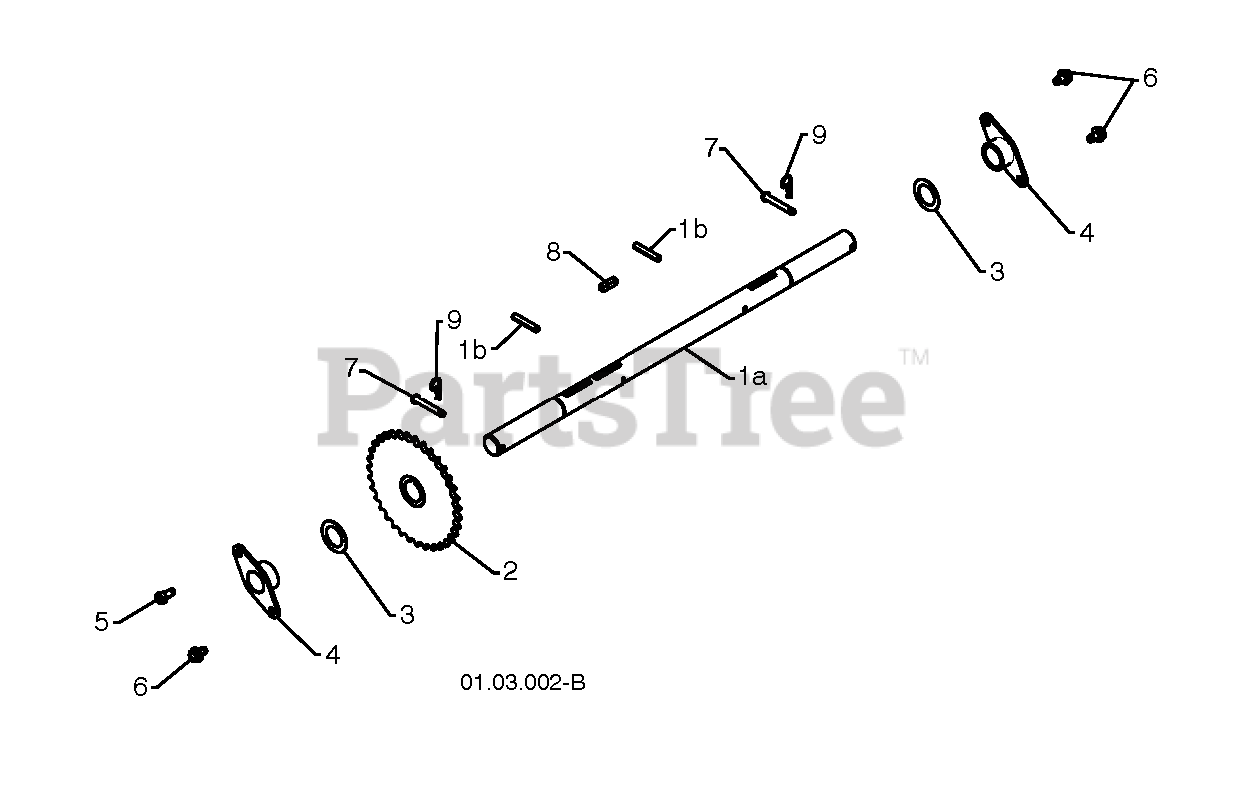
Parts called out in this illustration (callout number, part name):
1	AXLE.ASM.SHAFT.W/ROLLPIN.PS
2	SPROCKET.WELDMENT.AXLE.1.00
3	WASHER TRUST 1"
4	BEARING, AXLE
6	Screw 5/16-18 x 1/2 Hex, Self Tapping 5/16-18 x 1/2
7	RIVET
8	KEY, SQUARE 1/4 X .875
9	RETAINER M
